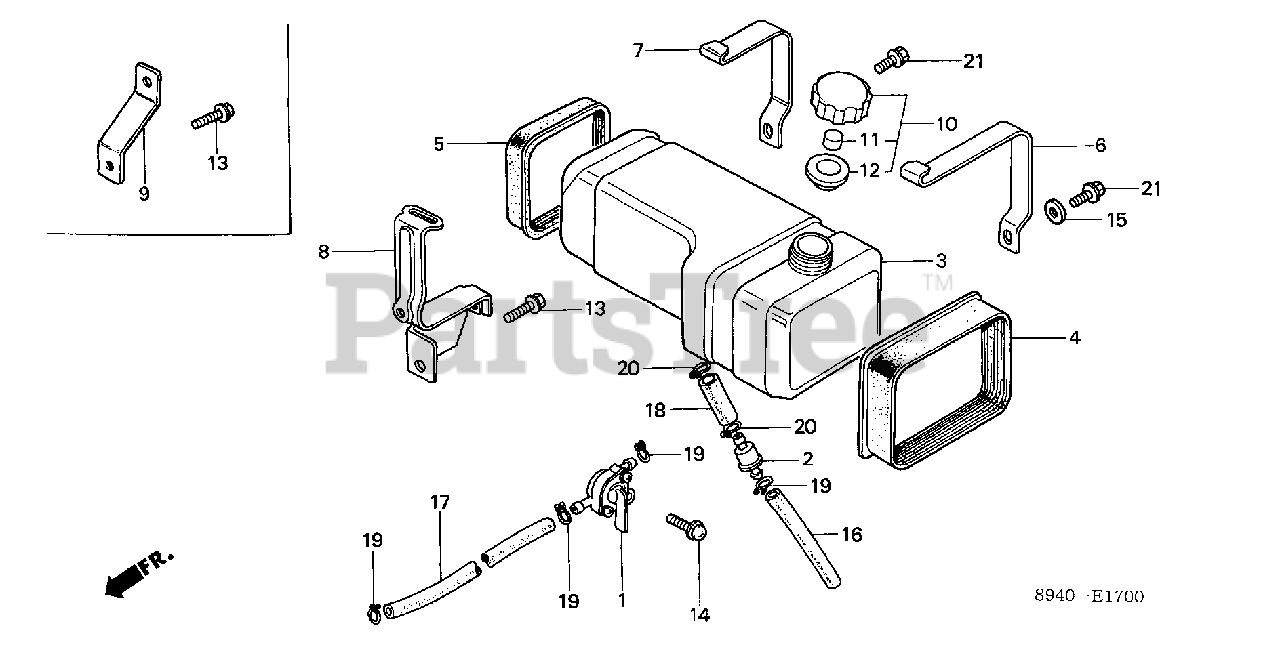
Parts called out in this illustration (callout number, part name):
1	PETCOCK ASSY. (NOT AVAILABLE)
2	STRAINER, FUEL
2	FILTER, FUEL
3	TANK, FUEL
4	RUBBER A, FUEL TANK MOUNTING
5	RUBBER B, FUEL TANK MOUNTING
6	BAND A, TANK MOUNTING (NOT AVAILABLE)
7	BAND B, TANK MOUNTING (NOT AVAILABLE)
8	STAY B, TANK
10	CAP, FUEL TANK
11	SPONGE, FUEL CAP BREATHER
12	GASKET, FUEL CAP
13	BOLT, FLANGE (6X12) (CT200)
14	SCREW-WASHER (5X12)
15	WASHER, PLAIN (6MM)
16	BULK HOSE, FUEL (4.5X3000) (4.5X100)
16	BULK HOSE, FUEL (4.5X3000) (4.5X115)
17	BULK HOSE, FUEL (4.5X3000) (4.5X195)
18	TUBE, FUEL
18	BULK HOSE, FUEL (5.5X3000) (5.5X40)
19	CLIP, TUBE (B8)
20	CLIP, TUBE (B10)
21	BOLT, FLANGE (6X12)
